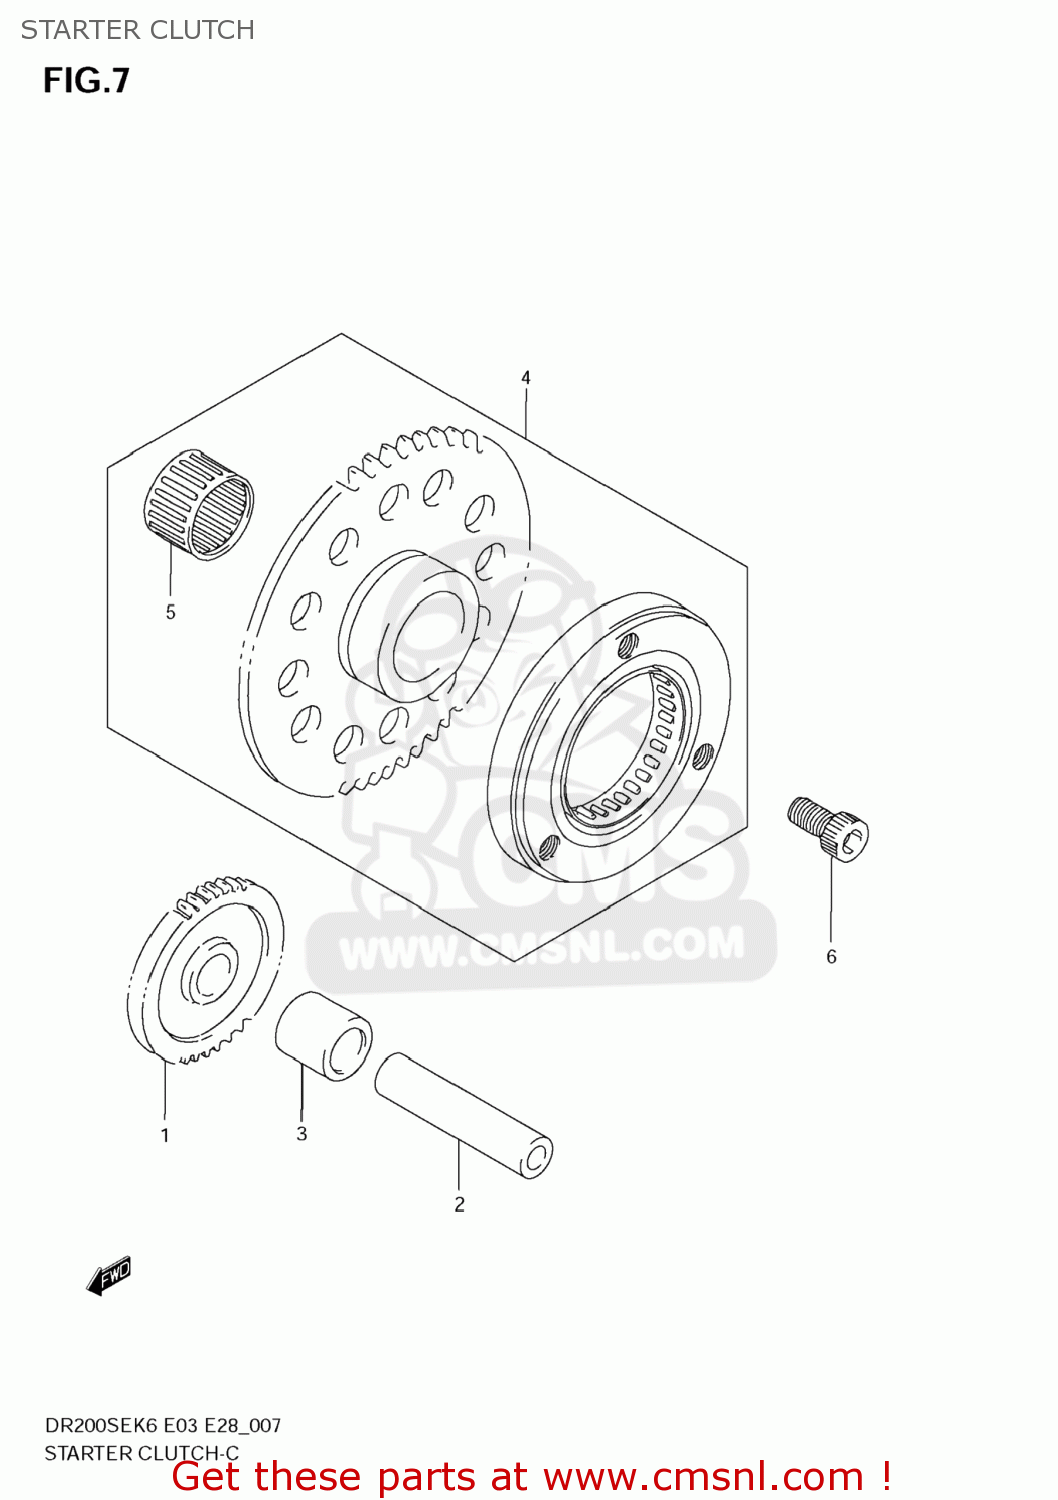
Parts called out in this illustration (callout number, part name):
1	GEAR,STARTER IDLE
2	PIN(7.4X13X56)
3	SPACER(13X19X19)
4	CLUTCH SET,STARTER
5	BEARING(22X28X16)
6	BOLT(8X16)
